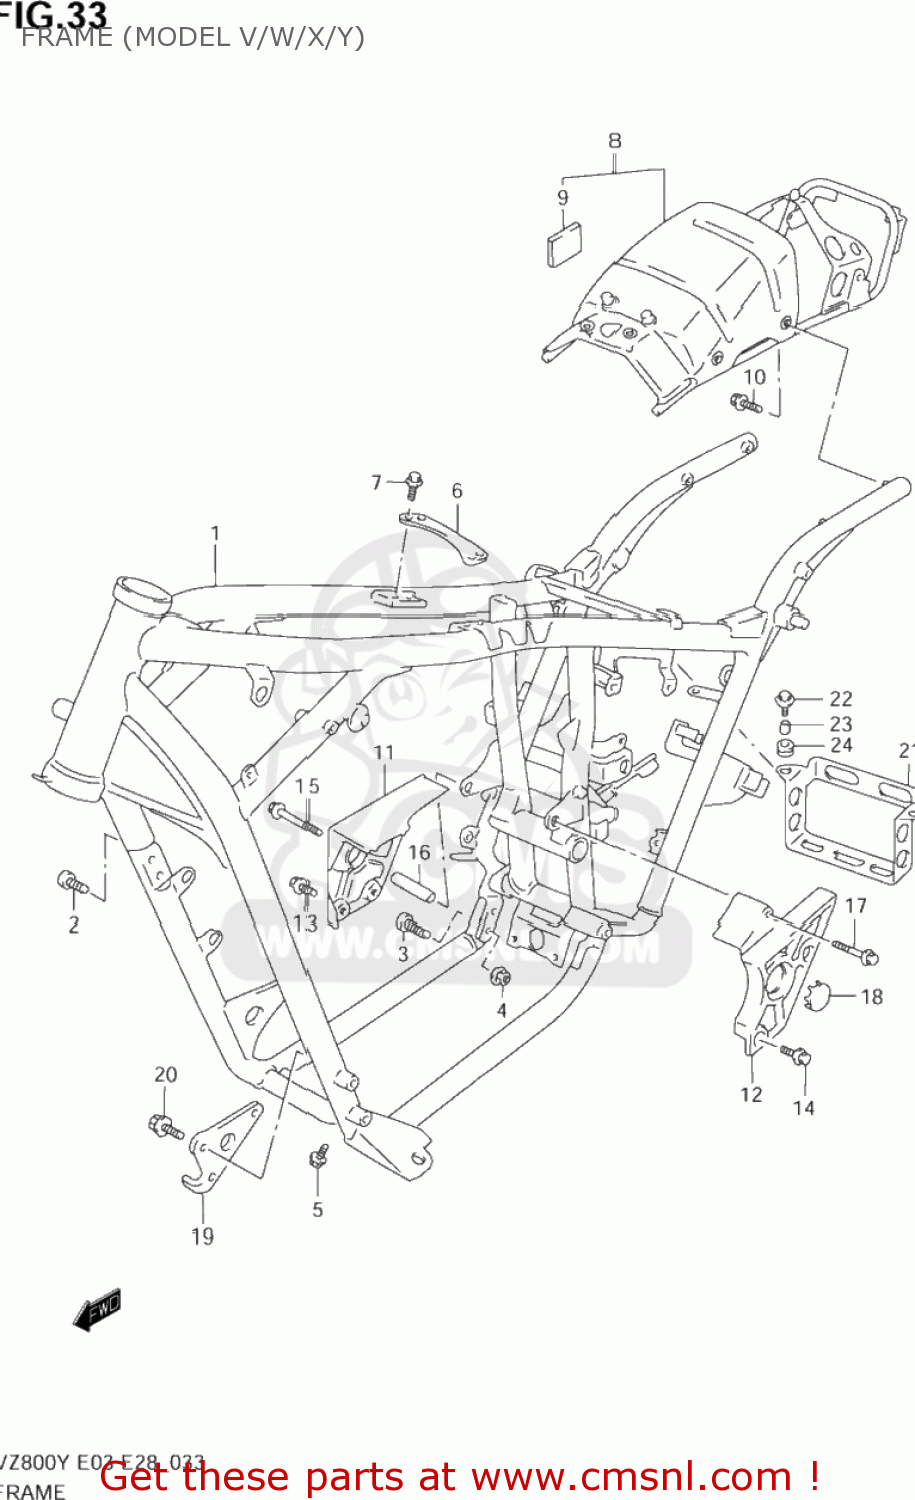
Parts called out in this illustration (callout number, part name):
1	FRAME COMP
2	BOLT
3	BOLT
4	NUT
5	BOLT
6	PLATE,FRAME BODY
7	BOLT
8	BRACE ASSY,RR FRAME
9	PAD
10	BOLT, FRONT
11	COVER,PIVOT,R
12	COVER,PIVOT,L
13	13-2
14	BOLT,PIVOT COVER
15	BOLT(8X16)
16	SPACER,PIVOT COVER,R
17	BOLT,PIVOT COVER UPR,L
18	CAP,RR SWINGING ARM PIVOT,R
19	PLATE,ENGINE MOUNT NO.1,L
20	BOLT
21	HOLDER,BATTERY
22	BOLT(6X16)
23	SPACER(6.5X9X8)
24	CUSHION
